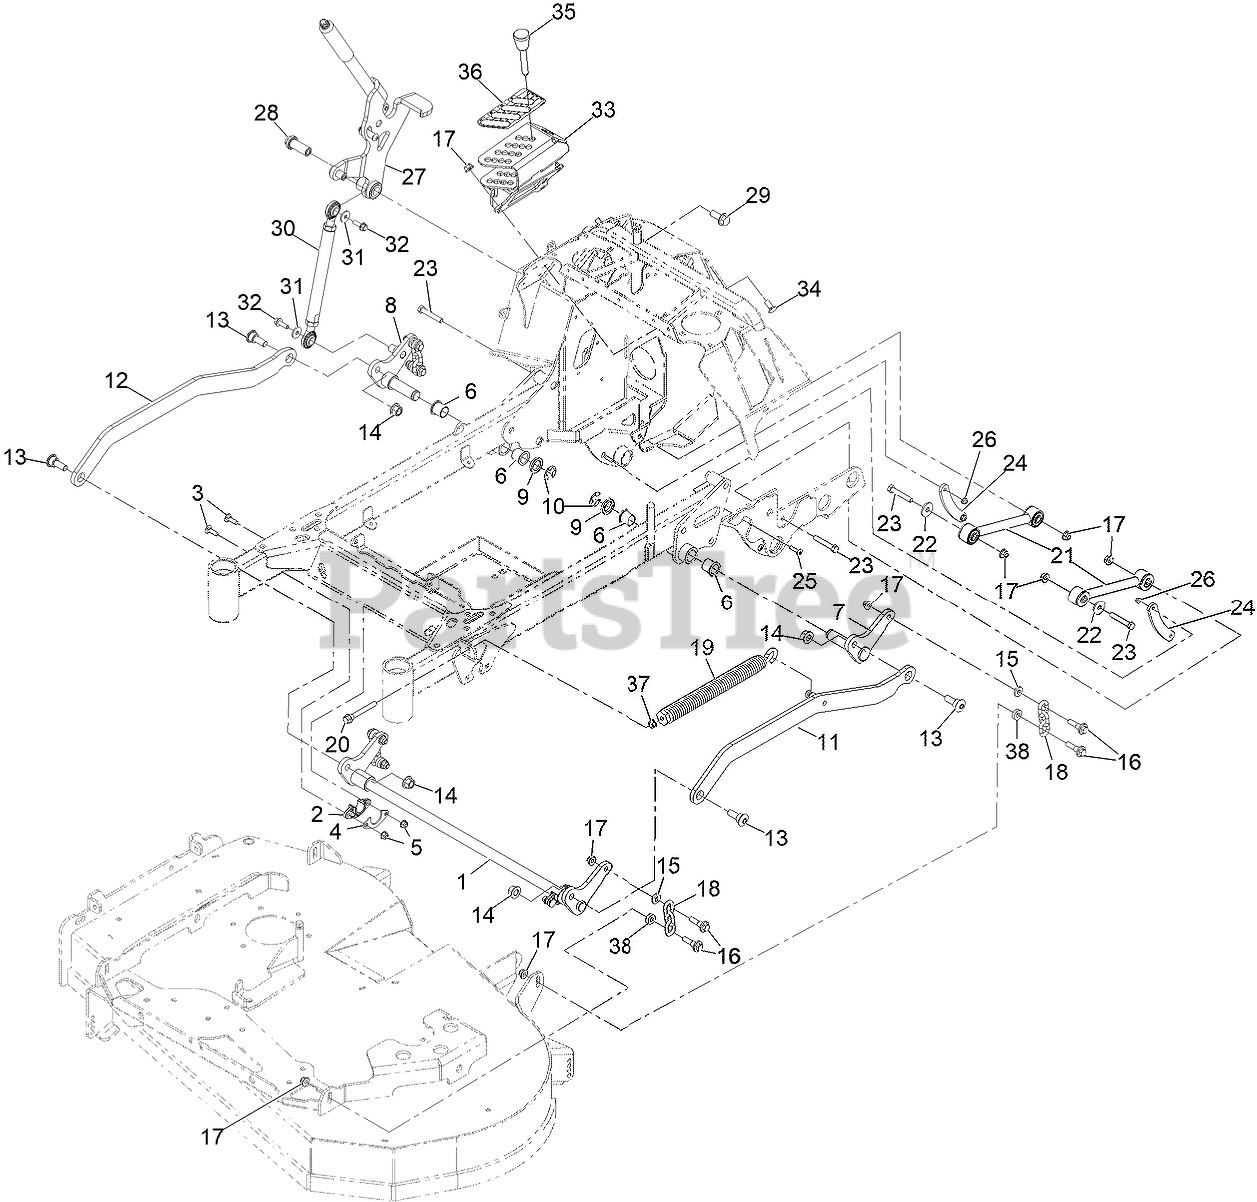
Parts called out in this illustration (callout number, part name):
1	WELD, HOC LIFT SHAFT
2	BUSHING-FLANGE
3	BOLT-CARR
4	GUSSET-LIFT, DECK
5	NUT-HF, NI
6	BUSHING, IGUS
7	WELD, BELLCRANK, LT RR
8	WELD, BELLCRANK, RT RR
9	SPACER, HOC PIVOT
10	RING-RETAINING, EXT
11	WELD, LIFT STRAP, LT
12	STRAP, LIFT RT
13	BOLT, SHOULDER
14	Nut-Lock 1/2-13
16	BOLT-SHOULDER
17	NUT-HF, NI
18	CHAIN-DECKLIFT
19	SPRING-EXTENSION
20	BOLT-SHOULDER
21	ASM, STRUT W/ BUSHINGS
22	WASHER
23	SCREW-HH
24	STRIP, RUB
25	SCREW-TTH
27	ASM, HOC LEVER
28	PIVOT, HOC LEVER
29	SCREW-HHF
30	ASM, LIFT ROD
31	WASHER-FRICTION
32	Screw-HHF
33	WELD, HOC INDEX
34	SCREW-CARR
35	PIN-HOC
36	DECAL-HEIGHT OF CUT
37	NUT-HHF, WHIZ
38	SPACER
